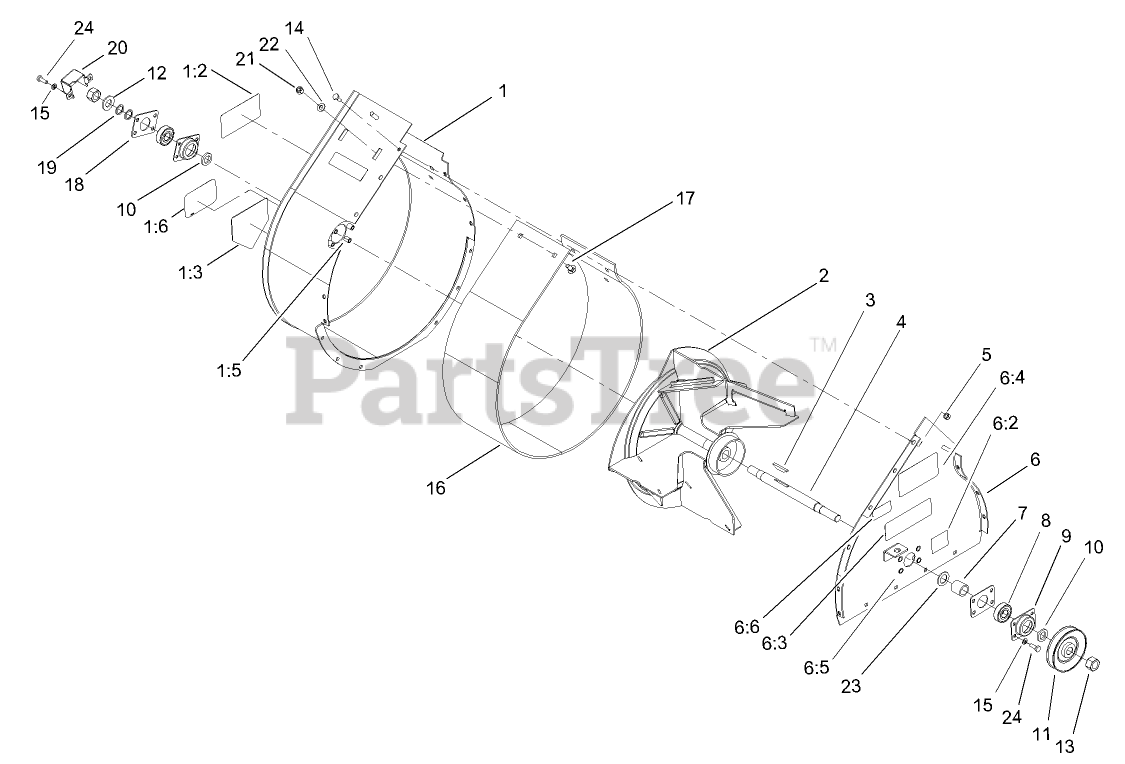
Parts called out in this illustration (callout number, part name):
1	BLOWER HOUSING ASM
1:2	DECAL-DANGER
1:3	DECAL-DANGER
1:5	INSERT-NUT
1:6	DECAL
2	IMPELLER ASM
4	Shaft-Blower
5	NUT-LOCK, NI
6	COVER PLATE ASM
6:2	DECAL-WARNING
6:3	DECAL-DANGER
6:4	DECAL-DANGER
6:5	INSERT-NUT
6:6	DECAL-PROTECTION, EAR
7	Spacer
8	BEARING-BALL
9	CUP-BEARING
10	SPACER-BEARING
11	Pulley ASM
12	WASHER-FLAT
13	NUT-HEX
14	SCREW-HH
15	WASHER-LOCK
16	STRIP-WEAR
17	BOLT-CARR
18	PLATE-COVER
19	WASHER-FLAT
20	Cover-Shaft
21	NUT-LOCK, NI
22	WASHER-PLAIN
23	WASHER-THRUST
24	SCREW-HH
